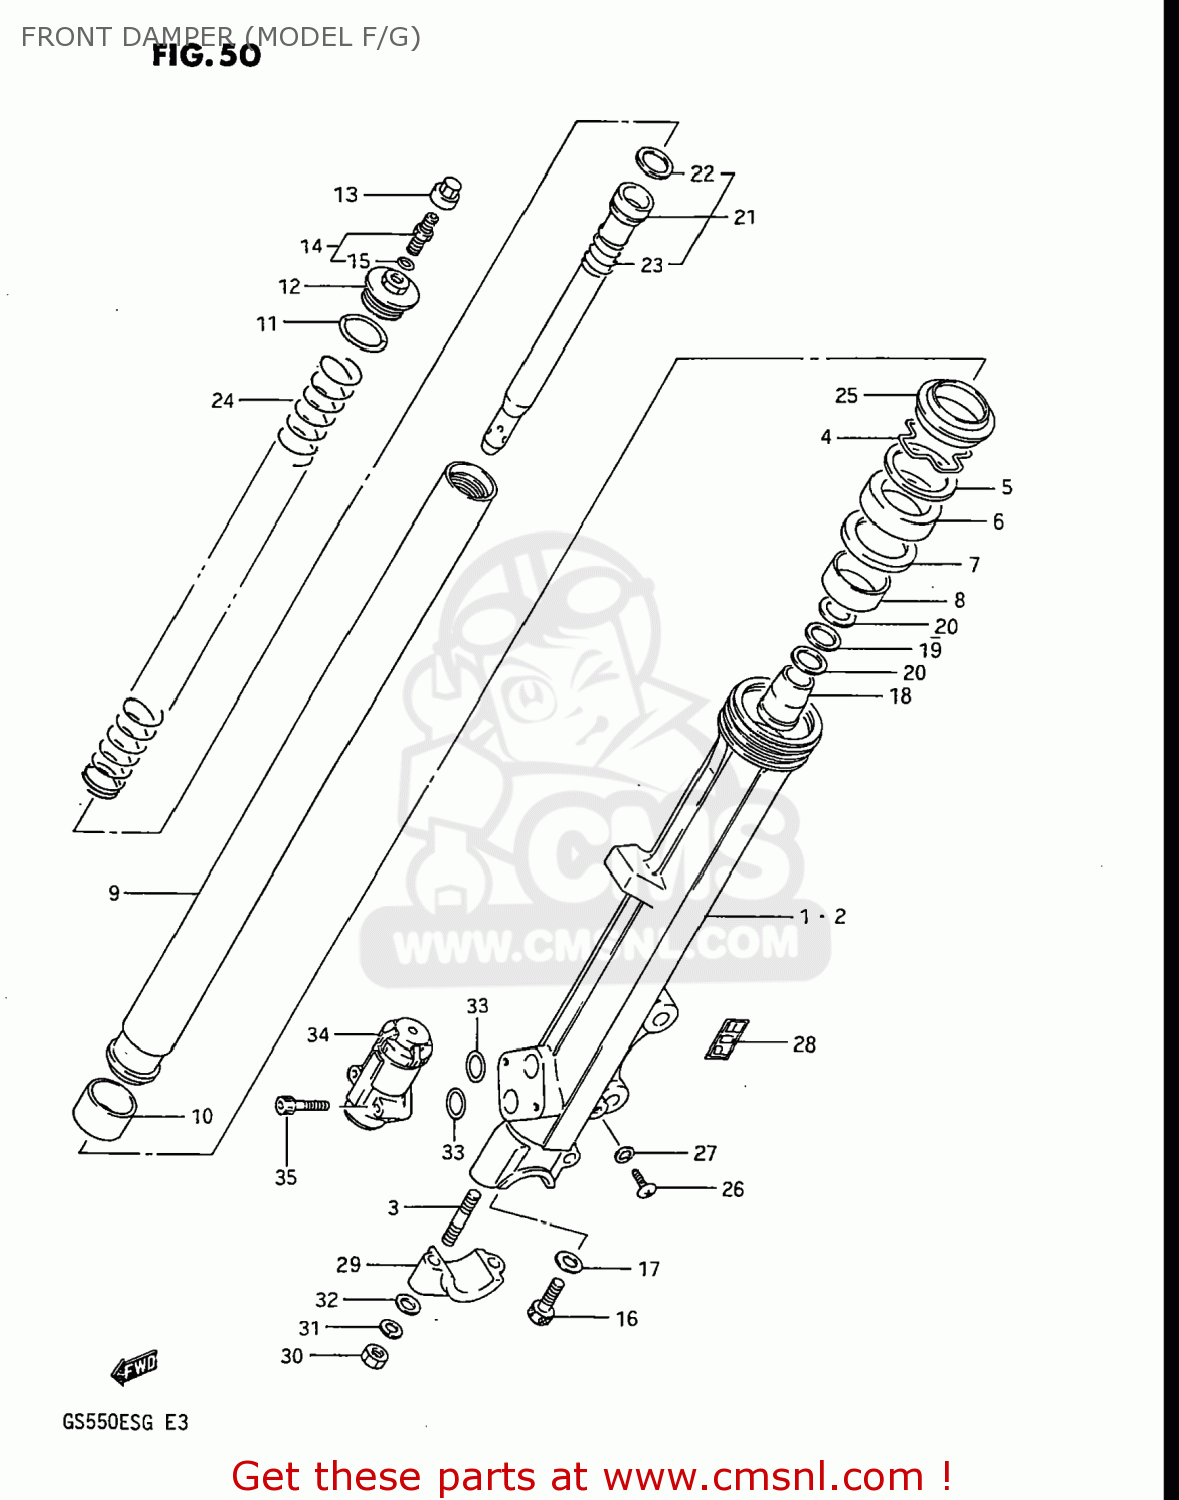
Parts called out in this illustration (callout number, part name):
1	TUBE,FORK,OUTER,RIGHT
2	TUBE,FORK,LEFT,OUTER
3	STUD 8X30
4	RING,STOPPER
5	WASHER. FRONT FORK
6	OIL SEAL,FRONT FORK
7	WASHER
8	METAL,SLIDE
9	TUBE,FORK,INNER
10	METAL,FR FORK PISTON
11	O RING
12	CAP
13	CAP,FRONT FORK AIR VALVE
14	VALVE,FRONT FORK AIR
15	O-RING
16	BOLT,FORK CYLINDER(10X25)
17	GASKET (NAS)
18	PIECE,OIL LOCK
19	WASHER
20	SPRING,LEAF
21	CYLINDER,FRONT FORK
22	RING,PISTON
23	SPRING,REBOUND
24	SPRING
25	SEAL,DUST
26	SCREW
27	GASKET,DRAIN,PLUG (NAS)
28	EMBLEM
29	HOLDER,AXLE
30	NUT
31	WASHER,LOCK,8.
32	WASHER
33	O RING
34	PDF ASSEMBLY
35	BOLT
